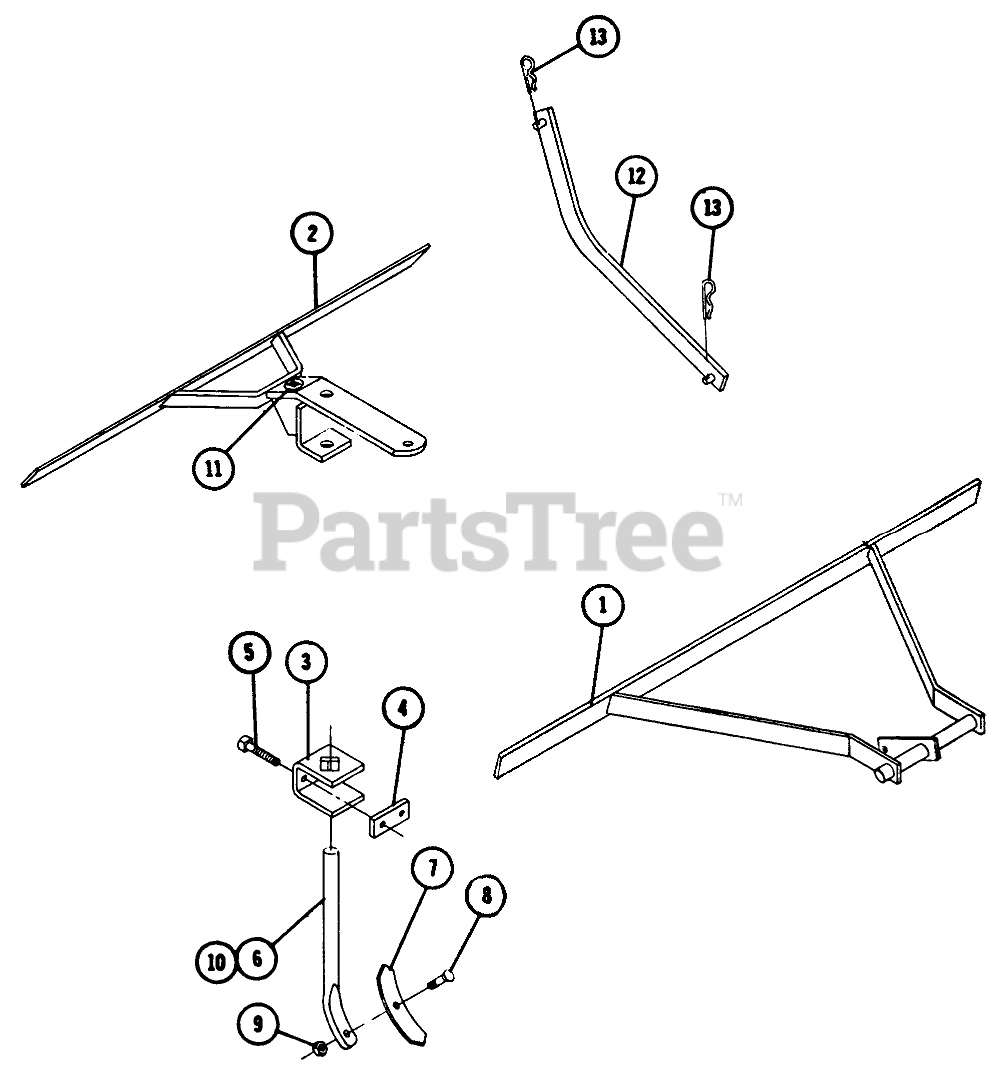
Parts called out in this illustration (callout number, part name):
1	Ass-y. Frame-Front
2	Frame Assembly-Rear
3	Clamp
4	PLATE
5	SQ HD CUP POINT SCR
6	Standard
7	Shovel
8	Plowbolt 3/8-16 x 1-1/2
10	STANDARD SHOVEL
11	Decal Steering Wheel
12	Ass-y. Lift Arm
13	Hairpin
